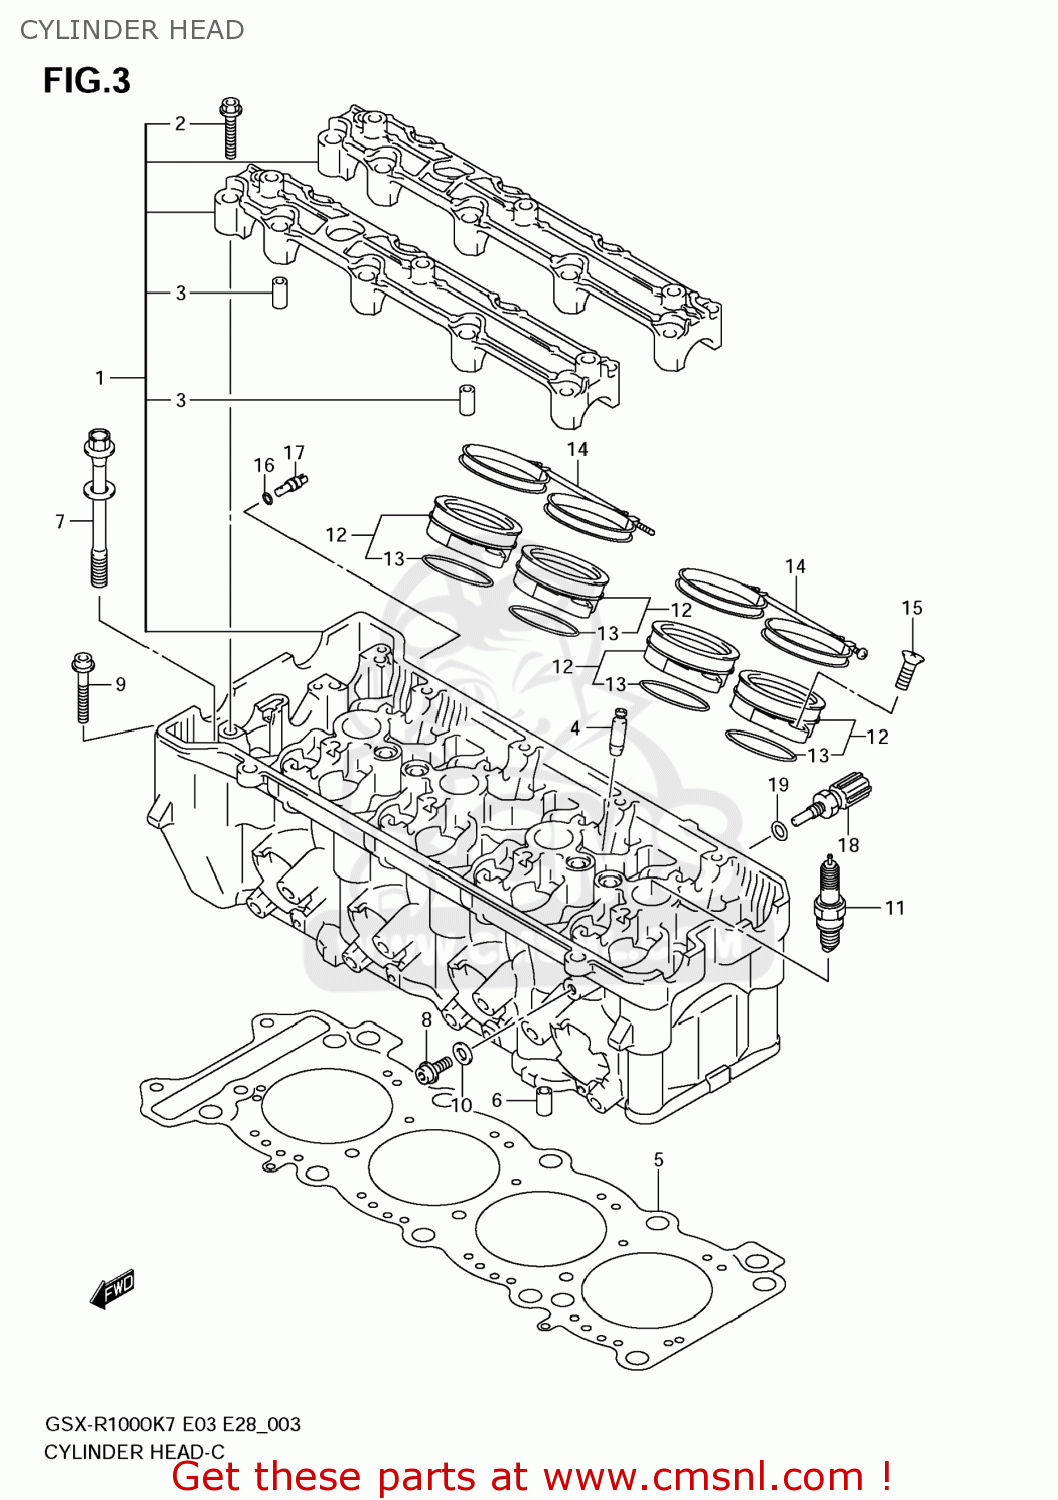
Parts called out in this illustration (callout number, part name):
1	HEAD ASSY,CYLINDER
2	BOLT(6X40)
3	PIN(6.2X8X16)
4	GUIDE,VALVE(OS:0.3)
5	GASKET,CYLINDER HEAD (NAS)
6	PIN
7	BOLT,CYLINDER HEAD(L:105)
8	BOLT(6X12)
9	BOLT
10	GASKET(5.8X13X1.2) (NAS)
11	PLUG,SPARK(IU27D)
12	PIPE ASSY,INTAKE
13	O RING(D:2.4,ID:47.2)
14	CLAMP COMP,INT
15	SCREW
16	O RING(D:1.2,ID:4)
17	JET(8)
18	SENSOR,WATER TEMP
19	GASKET(12X17X1) (NAS)
